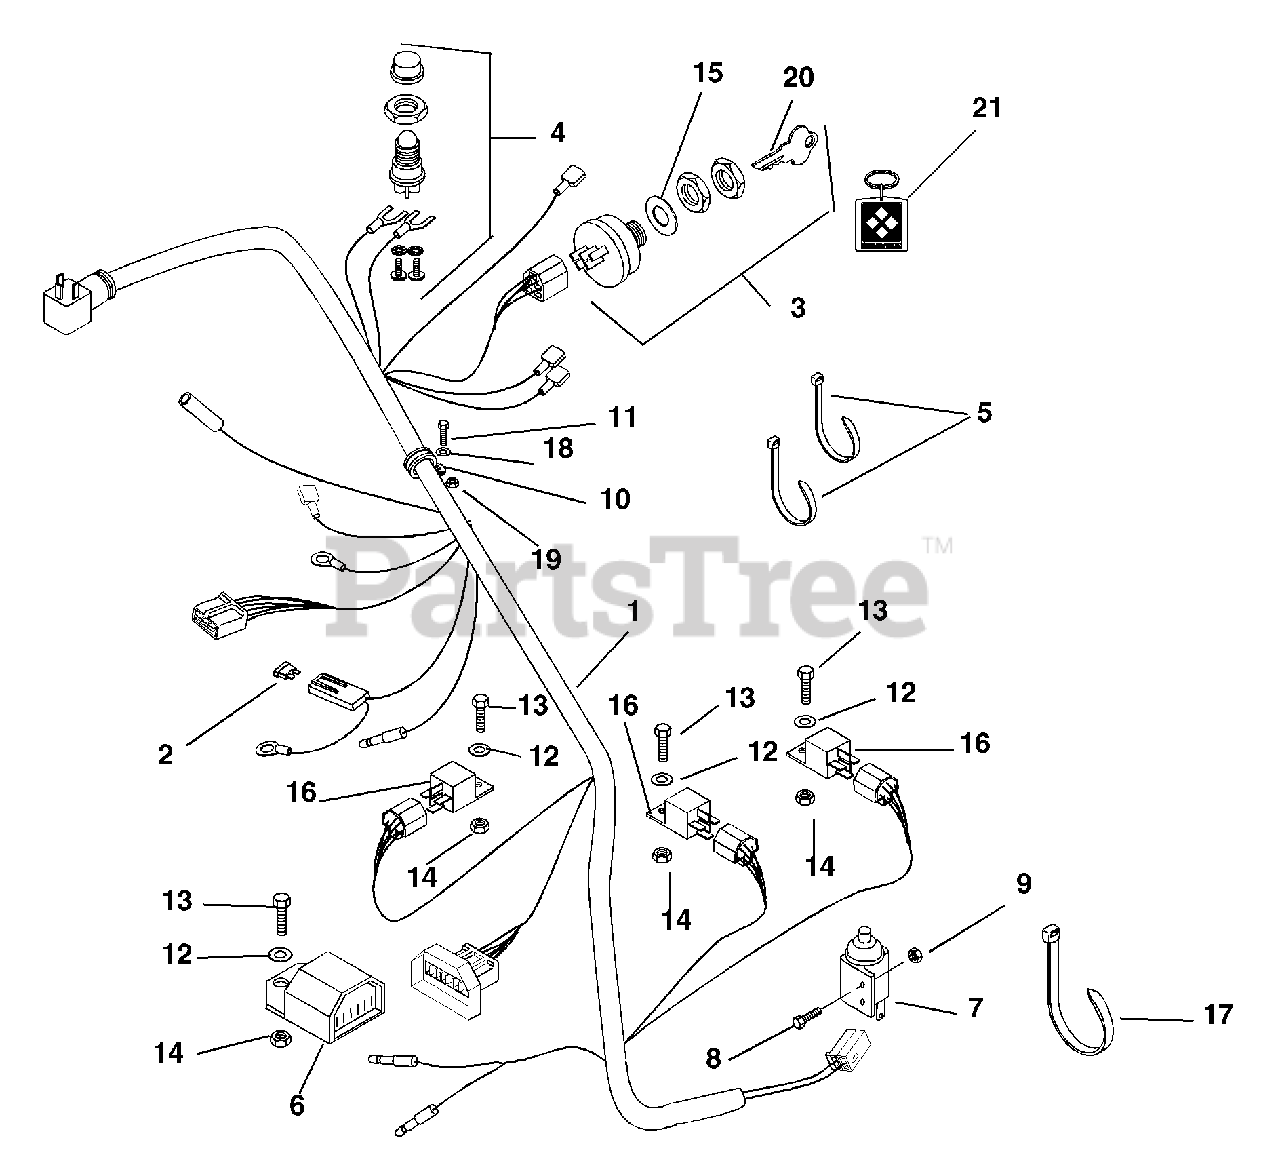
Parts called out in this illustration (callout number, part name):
1	Harness-Wiring 20 H.P. Honda 20 AMP
2	Fuse-25 Amp
3	Switch-Ignition
4	Switch
5	Tie- Wrap 15.25"
6	Module-Interlock Delay
7	Switch-Operator Presence
8	Bolt-Hex M5-.8 x 16
9	Nut-Locking-Nylon M5-.8
10	Clamp-Cushioned Steel
11	Bolt-Hex M6 x 1.0 x 25
12	Washer-Flat-Steel .194 x .492 x .047
13	Bolt-Hex M5 x .80 x 16
14	Nut-Locking-Nylon M5 x .80
15	Washer-Flat-Steel .812 x 1.50 x .135
16	Relay
17	Cable-Tie Large 5-1/2
18	Washer-Flat-Steel .281 x .62 x .065
19	Nut-Locking Nylon M6-1
20	Key, Ignition Honda
21	Key Chain
